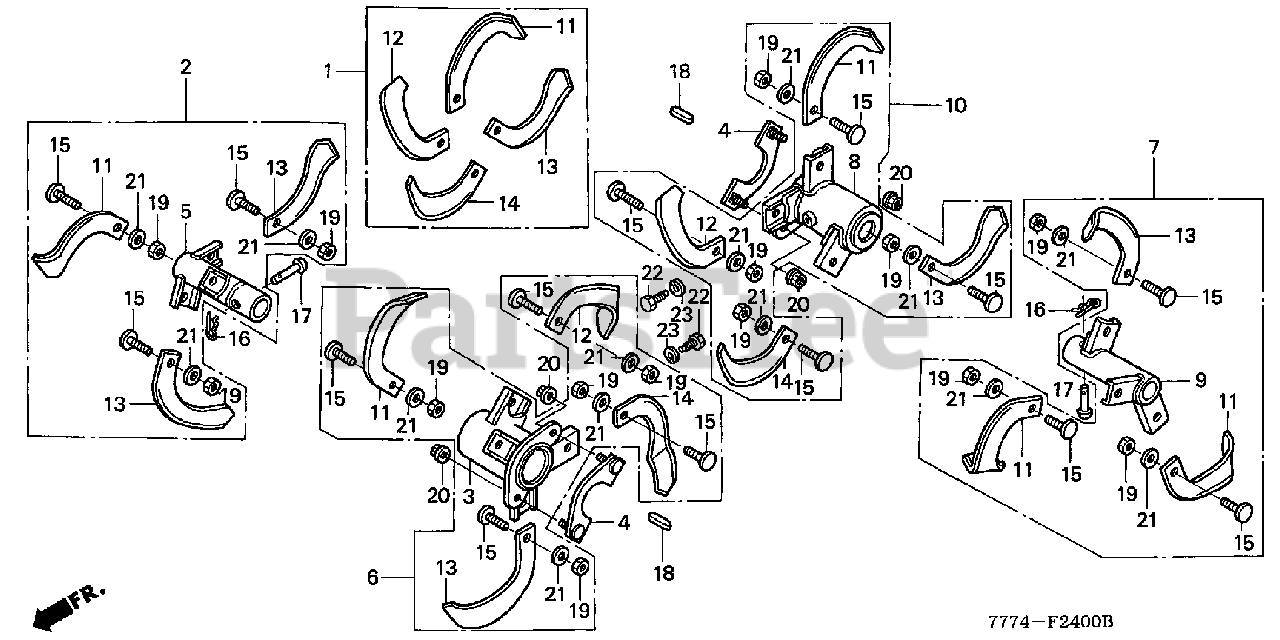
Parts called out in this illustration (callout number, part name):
1	TINE KIT, ROTARY
2	TINE ASSY., R. (OUTER)
3	HOLDER, R. INSIDE
4	WASHER, SPECIAL FLANGE
5	HOLDER, R. (OUTER)
6	TINE ASSY., R. INSIDE
7	TINE ASSY., L. (OUTER)
8	HOLDER, L. INSIDE
9	HOLDER, L. (OUTER)
10	TINE ASSY., L. INSIDE
11	TINE A, ROTARY
12	TINE, R. ROTARY
13	TINE B, ROTARY
14	TINE, L. ROTARY
15	BOLT, TINE FIXING (10X22)
16	PIN, SNAP (10MM)
17	PIN (10X45)
18	KEY (7X7X30)
19	NUT, HEX. (10MM)
20	NUT, FLANGE (8MM)
21	WASHER, SPRING (10MM)
22	BOLT, SPECIAL (10X16)
23	WASHER, SPRING (10MM)
